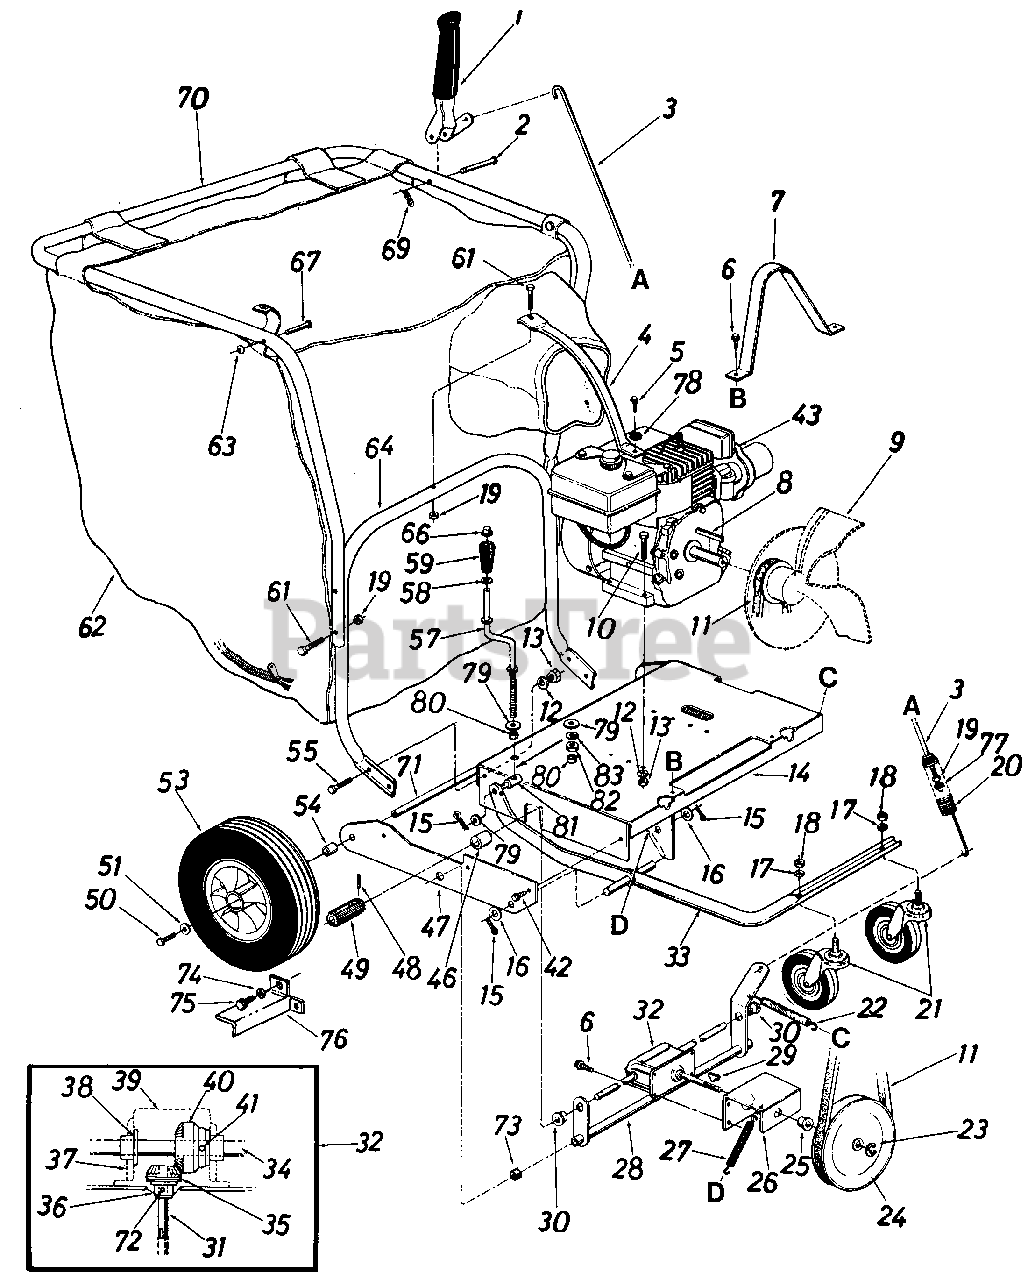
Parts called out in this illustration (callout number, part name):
1	GRIP ASSY-CLUTCH
2	PIN-CLEVIS
3	ROD-LOCKOUT
4	BRACE-HANDLE PAINTED
6	SCREW-HEX L-WASH HD
10	SCREW-HEX 5/16-18 X 1.50
11	BELT-V 1/2 X 26
12	WASHER-LOCK-5/16
13	NUT-HEX 5/16-18
16	WASHER-FL-.640ID X 1.24OD X .06HDN
17	WASHER-LOCK-1/2
18	NUT-HEX 1/2-13
19	NUT-HEX CENTER L-1/4-20
21	WHEEL ASSY-CASTER
22	SPRING-EXTENSION
23	RING-E FOR .500 SHAFT
25	BEARING-FLANGE
28	BRACKET ASSY-CLUTCH
29	KEY-WOODRUFF #2-3/32X1/2 DIA-HDN
30	BEARING-HEX FLANGE
31	SHAFT-PINION
32	GEAR CASE ASSY-COMP
35	PINION-14T
36	BEARING-FLANGE .503 ID
37	KIT-GEAR BOX ASSY
38	BEARING-FLANGE
39	COVER-GEAR BOX
40	GEAR-BEVEL-.62 ID 28T
41	PIN-SPRING SPIR 3/16 X 1.25
42	SCREW-HEX HD TAP
43	ENGINE
46	SPACER
49	PINION-DRIVE
50	SCREW-HEX 5/16-24 X .62 SPEC PLAST
51	WASHER-FL-.344 ID X .88 OD X .063
53	WHEEL ASSY W/TIRE
55	SCREW-HEX 5/16-18 X .75
57	CRANK-HGT ADJUSTMENT
58	WASHER-FL-.385 ID X .62 OD X .033
59	KNOB W/38 HOLE-BLACK
61	SCREW-HEX 1/4-20 X 1.75
62	BAG-VACUUM FELT
63	NUT-SPECIAL
66	PUSH NUT 3/8" Dia.
67	STUD PIN .250" DIA. X 1.75"
69	INTERNAL COTTER PIN 3/8" DIA.
70	UPPER HANDLE (PAINTED)
72	PIN-SPRING ROLL 5/32 X 1.12
73	SPACER
74	WASHER-SPRING.270 ID X.51 OD X.030
75	SCREW-HEX B-TAP 1/4 X .38
78	WASHER-BELL .337 X .867 X .057
79	WASHER-FL-.385 ID X .87 OD X .06
80	SPACER
81	FERRULE
82	NUT-HEX SPECIAL
83	WASHER-LOCK-3/8
14530-0499	PLATE-SIDE-RH - CUB BEIGE (0499)
14530-0637	PLATE-SIDE-RH - POWDER BLACK (0637)
14530-0662	PLATE-SIDE (RH) - OYSTER GRAY (0662)
16273-0498	Double Caster Arm Assembly, Black - OLD CUB YELLOW (0498)
16273-0637	Double Caster Arm Assembly, Black - POWDER BLACK (0637)
16273-0638	Double Caster Arm Assembly, Black - MTD/TROY-BILT RED (0638)
16273-0648	Double Caster Arm Assembly, Black - TECH GRAY (0648)
16273-0662	Double Caster Arm Assembly, Black - OYSTER GRAY (0662)
16273-0674	Double Caster Arm Assembly, Black - YARDMAN YELLOW (0674)
16273-0691	Double Caster Arm Assembly, Black - BLACK JACK (0691)
16273-0709	Double Caster Arm Assembly, Black - MASTERCRAFT GREEN (0709)
16454-0638	FRAME ASSEMBLY - MTD/TROY-BILT RED (0638)
